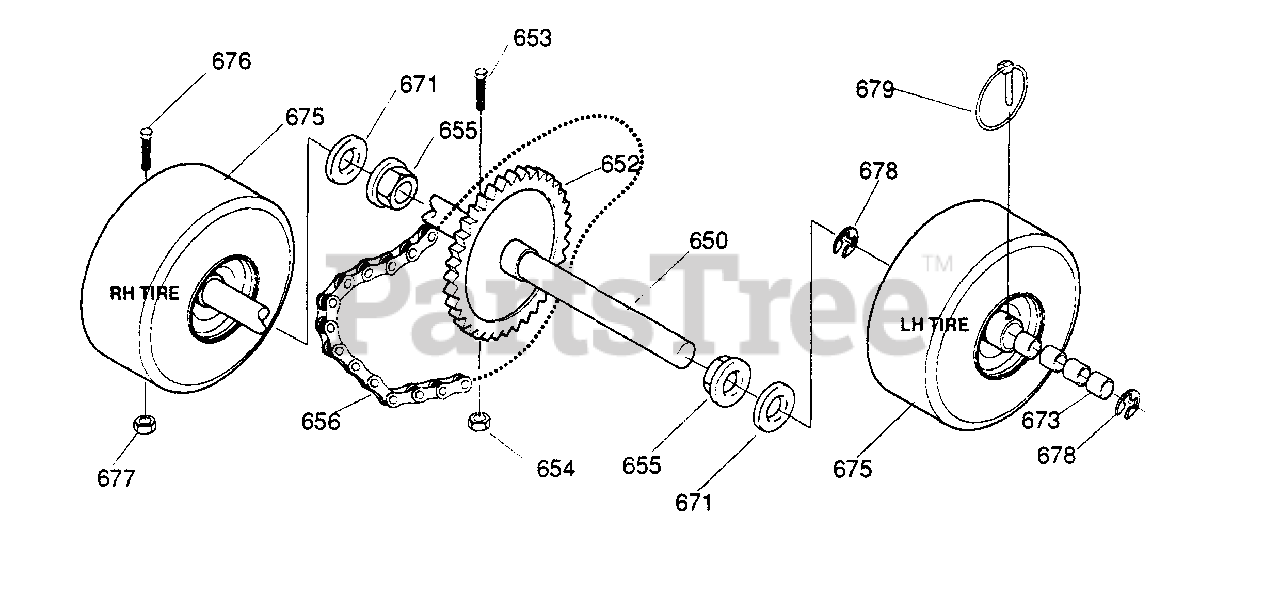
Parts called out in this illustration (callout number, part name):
650	SHAFT, AXLE
652	SPRKT, HUB #40-35Tx .75ID
653	SCREW, 1/4-20X2.25
654	NUT, 1/4-20 REGHEXCTRLK
655	BEARING, FLANGED
656	CHAIN, ROLLER #42x40PITCHES
671	FLATWASHER,.765x1.12x.06
673	BEARING, FLANGE
675	TIRE & RIM, PU 16x4.8x4
676	SCREW, SHR 1/4-200.75
677	NUT, 1/4-20 REGHEXCTRLK
679	PIN, KLIK.25x1.38 DIA
